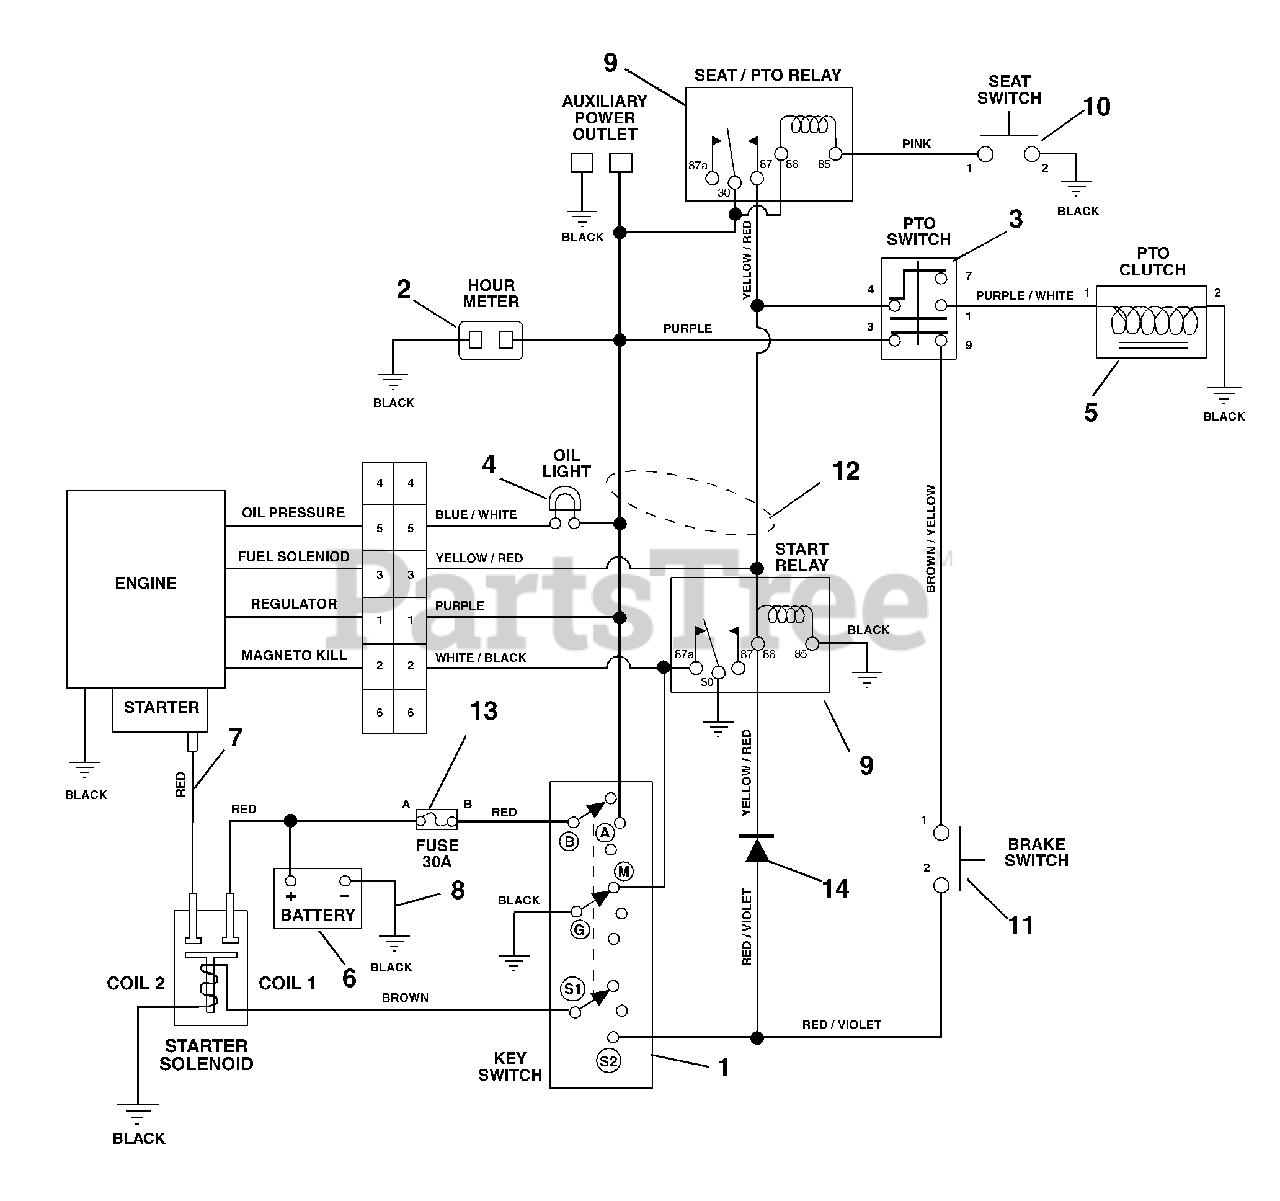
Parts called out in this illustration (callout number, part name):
1	Key Switch
2	Hour Meter
3	Switch-Clutch With Retainer Ring
4	Light-Indicator
5	Electric Clutch
6	Battery with Tube
7	Cable-Battery To Solenoid
8	Ground Cable
9	Relay
10	Seat Switch
11	Switch-Single Pole
12	Harness-Kohler
13	Fuse, 30 Amp
14	Molded Diode Plug-Black 1-Amp
